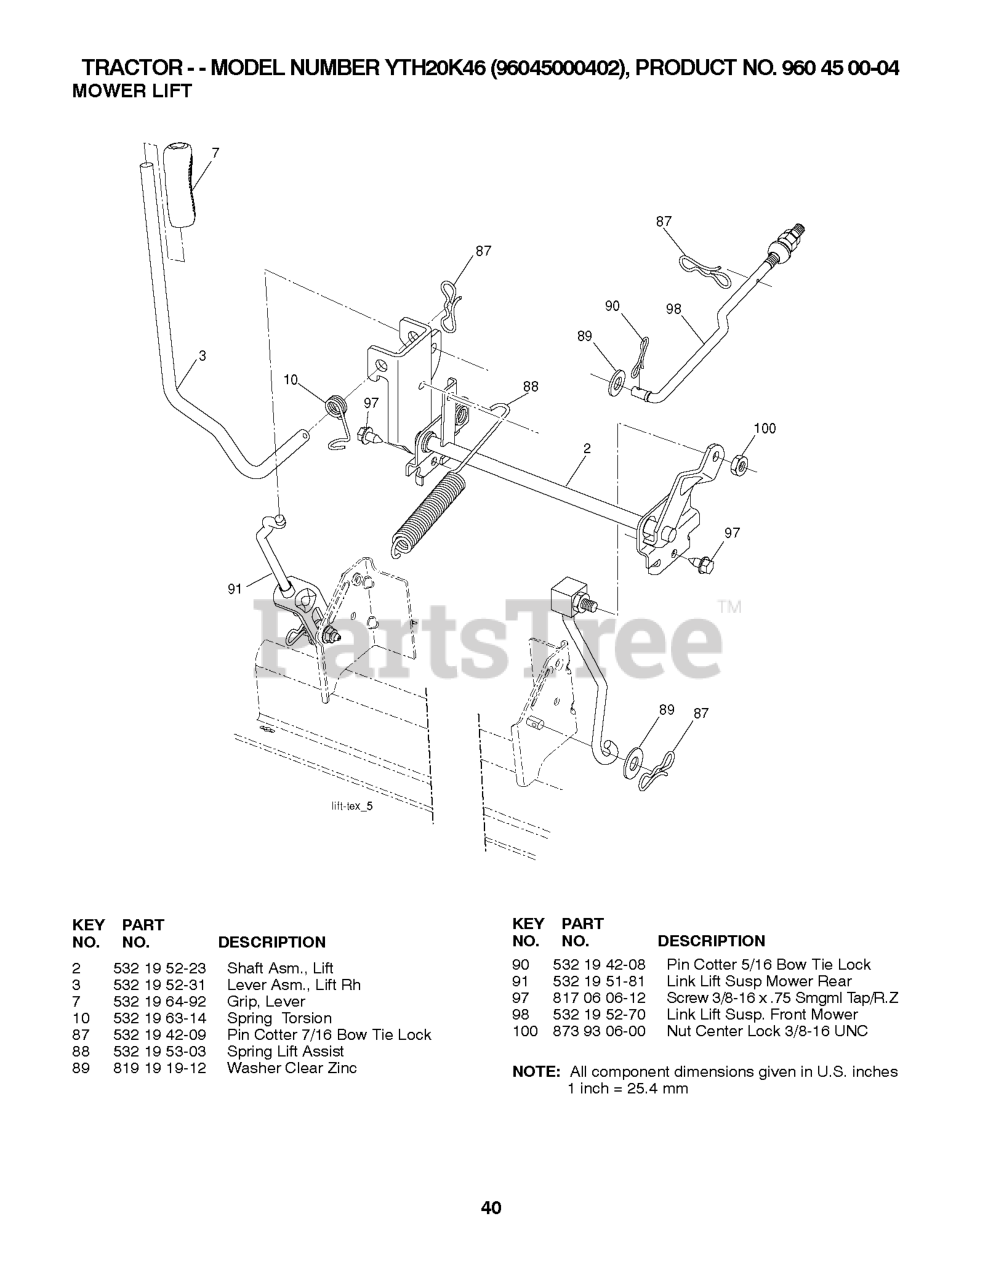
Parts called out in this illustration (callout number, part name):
2	SHAFT.ASM.LIFT.CROSS.H
3	LEVER.LIFT.HANDLE.LT
7	GRIP.LEVER.5625.ID
10	SPRING.TORSION.LIFT.HANDLE
87	PIN.COTTER.7/16.BOW TI.
88	SPRING.LIFT.ASSIST.LT
89	WASHER.CLEAR.ZINC
90	PIN.COTTER.5/16.BOW TI
91	LINK.ASM.LIFT.REAR
97	SCREW 3/8-16X3/4
98	LINK.ASM.SUSP.FRONT.MW
100	LOCKNUT
